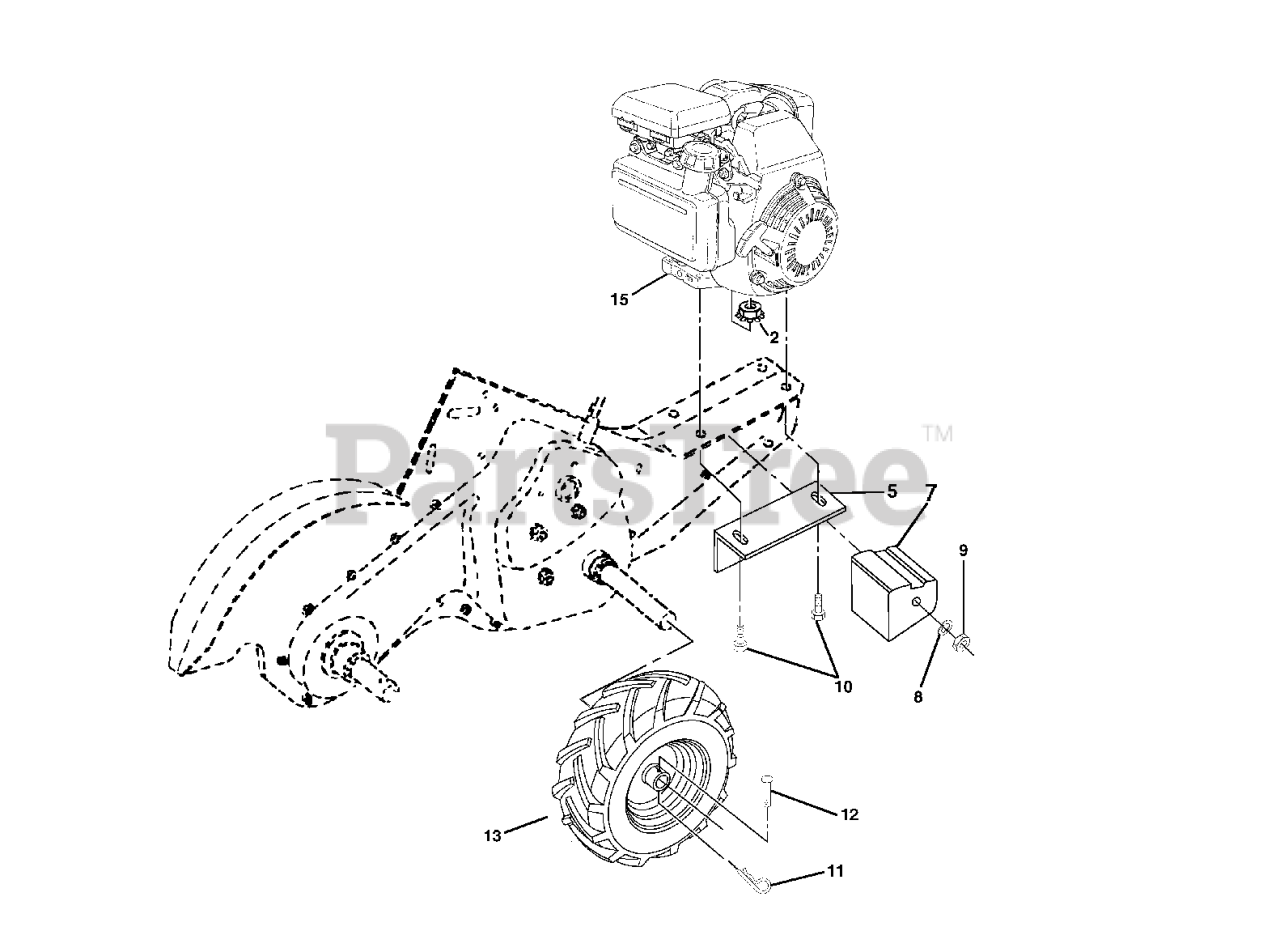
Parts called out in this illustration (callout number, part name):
2	LOCKNUT-FLANGE 5/16-18
5	DNO BRACKET RH CRT
7	COUNTERWEIGHT, RH
8	WASHER, LOCK 3/8
9	NUT.HEX.3/8-16UNC
10	BOLT
11	RETAINER M
12	RIVET,DRILLED
13	TIRE.13X5-6.CHEVRON.TILLER
